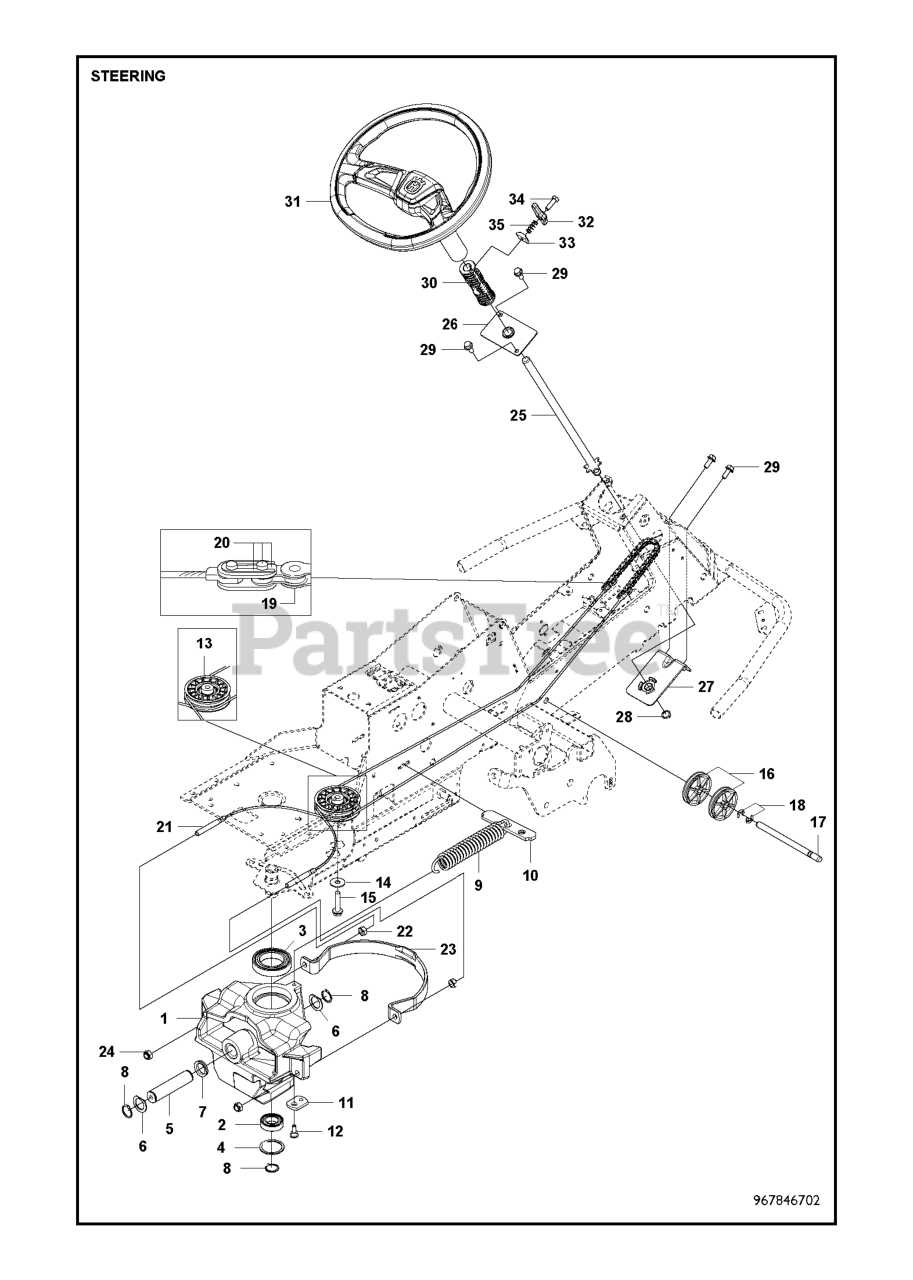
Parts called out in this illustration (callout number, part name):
2	Ball Bearing 6005-2rs
3	BALL BEARING 6010 2RS1
4	CIRCLIP SGH 47
8	RETAINING RING SGA 25
15	COLLAR SCREW
18	RETAINING RING
19	STEERING CHAIN
23	WIRE GUIDE
24	NUT
26	BRACKET STEERING ASSY WITH BUS
27	BRACKET STEERING ROD ASSY
28	RETAINING RING SGA 15
30	DRIVER STEERING WHEEL
33	FIXING PLATE
35	SPRING STEERING ADJUSTMENT
